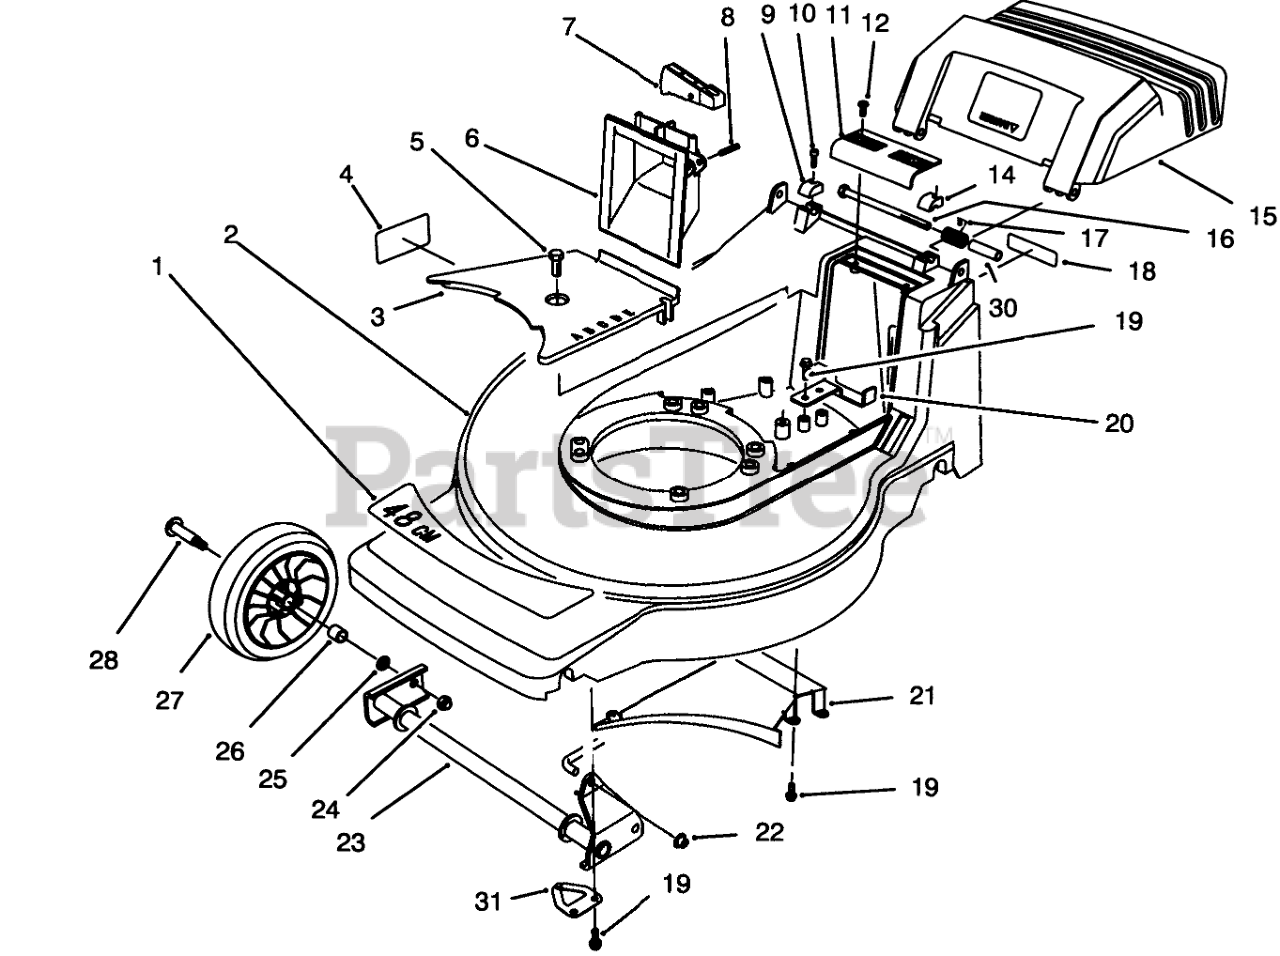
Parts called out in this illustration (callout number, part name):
1	DECAL - DECK 48 CM
2	Housing-48cm (Incl. Ref. #4)
3	BELT COVER
4	DECAL - DIN/DANGER
5	SCREW-HWHTF
6	GRIP - LOWER
7	TRIGGER - HOC
8	PIN-SPIRAL
9	CAP-HINGE BOLT, RH
10	SCREW-HSH
11	GRIP-UPPER
12	SCREW-PPH, PLASTITE
14	CAP-HINGE BOLT, LH
15	Door Discharge
16	SCREW-HH
17	SPRING-DOOR
18	DECAL FRENCH REGUL.
19	SCREW-HWH
20	REAR BELT GUIDE
21	Ramp-Discharge
22	NUT-PUSH
23	FRONT PIVOT WA
24	NUT-HEX
25	WASHER
26	BUSHING
27	Wheel & Tire Assembly (Incl. Ref. #28)
28	BOLT-WHEEL
30	SPACER-DOOR
31	SHAFT RETAINER ASM
